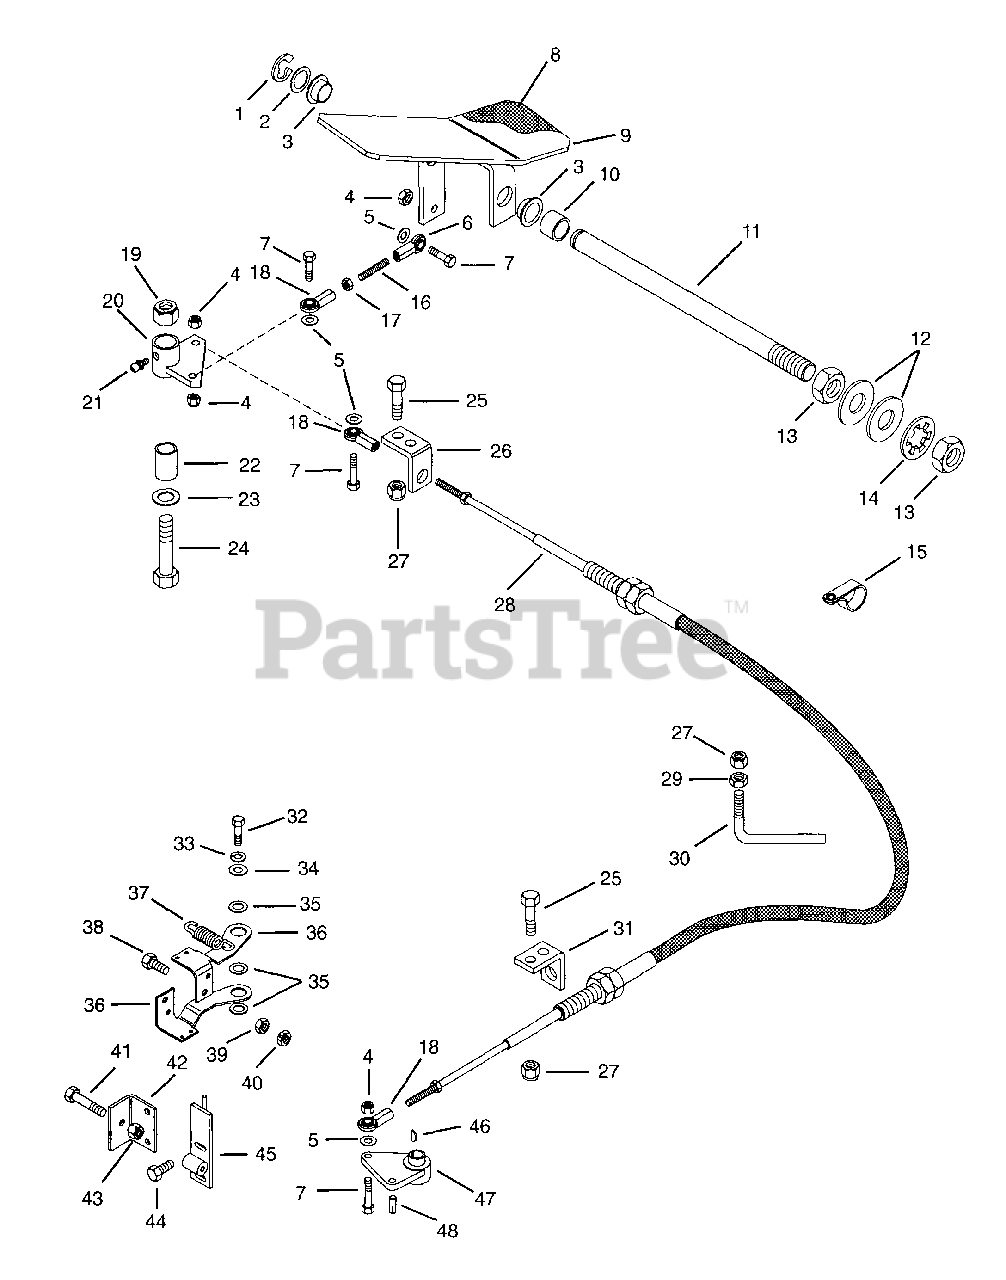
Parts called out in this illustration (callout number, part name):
1	Ring-Retaining-External .574 x .050
2	Bearing-Needle-Thrust .752 x 1.24 x .031
3	Bushing-Flange .762 x 1.0 x .580 x 1.48
4	Nut-Locking-Center .25-20
5	Washer-Flat-Steel .281 x .620 x .065
6	Rod End Left Hand
7	Bolt-Hex .31-18 x 1.75 Grade 5
8	Cover-Pedal
9	Weldment-Pedal
10	Bushing-Sleeve .782 x 1.00 x .710
11	Shaft-Pedal
12	Washer-Flat-Steel .812 x 1.50 x .139
13	Nut-Jam .75-16
14	Washer-Lock Internal .750
15	Clamp-Steel 1.0
16	Rod
17	Nut-Jam .25-28
18	Rod End-Female 1/4-28
19	Nut-Locking-Center .50-13
20	Weldment-Lever
21	Fitting-Lube .25-28 x .256
22	Spacer .562 x .855 x 1.56
23	Washer-Flat-Steel .50 x 1.25 x .083
24	Bolt-Hex .50-13 x 2.50 Grade 5
25	Bolt-Hex .38-16 x 1.00 Grade 5
26	Bracket-Cable
27	Nut-Locking-Center .38-16
28	Cable-Forward-Reverse
29	Nut-Jam .375-16
30	Rod-Cable Guide
31	Bracket-Cable
32	Bolt-Hex .25-20 x 1.50 Grade 5
33	Washer-Locking .25 x .062
34	Washer-Flat-Steel .281 x 1.250 x .048
35	Washer-Flat-Steel .760 x 1.25 x .030
36	Lever-Neutral
37	Spring-Tension .075 x .75 x 2.25
38	Bolt-Hex .31-24 x .75 Grade 5
39	Nut-Jam .312-24
40	Nut-Locking-Center .312-24
41	Bolt-Hex .31-18 x 1.25
42	Bracket
43	Nut-Locking-Nylon .312-18
44	Screw-Tapping .31-18 x .88 Hex Washer Head
45	Weldment-Neutral Stop
46	Key-Woodruff .13 x .50
47	Arm-Transmission Control
48	Pin-Groove .250 x .75
